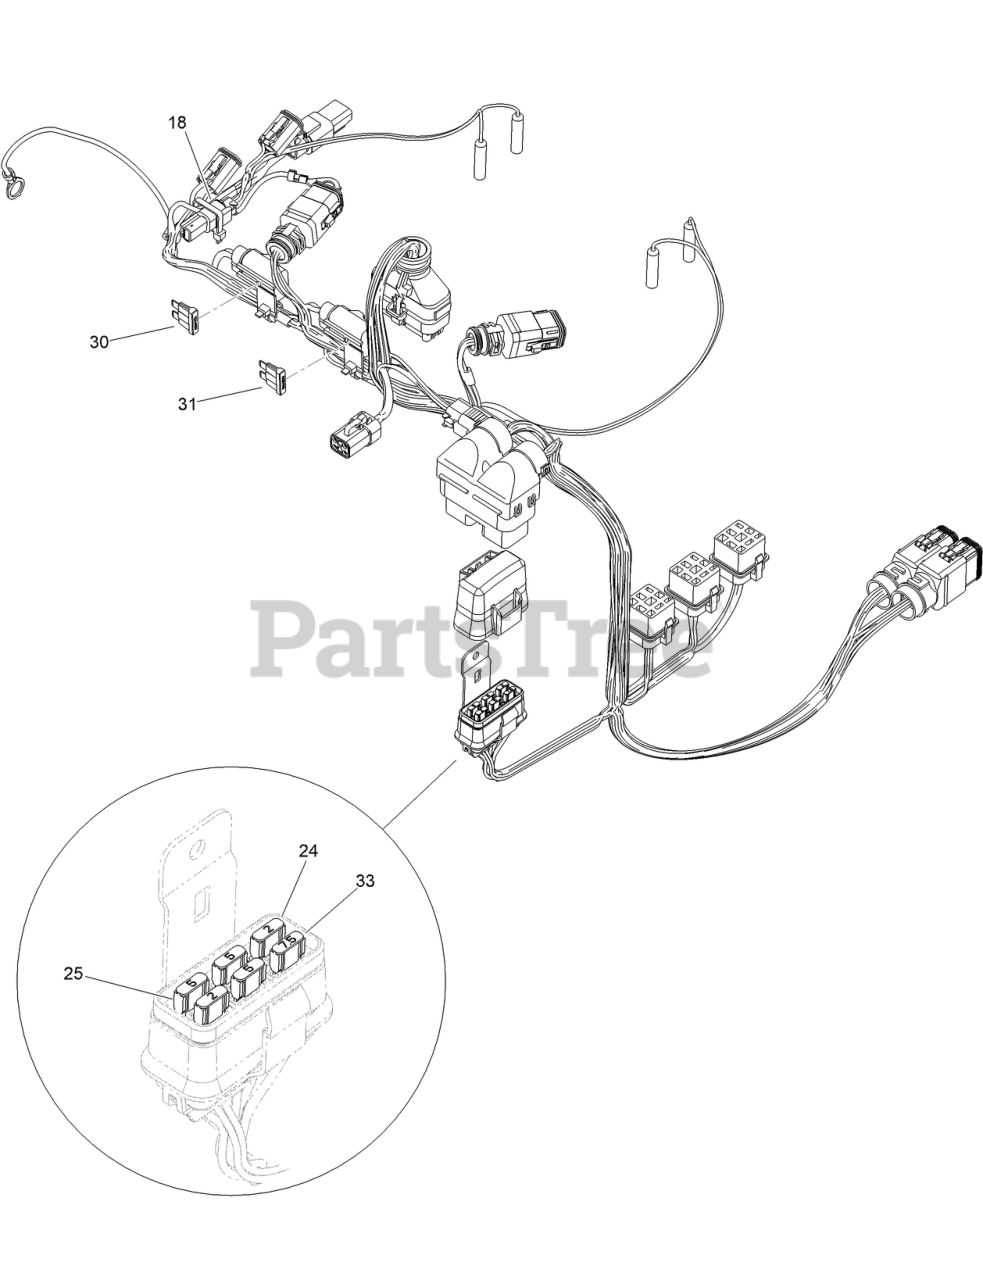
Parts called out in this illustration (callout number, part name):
18	RESISTOR-120 OHM
24	FUSE-MINI BLADE, 2 AMP
25	FUSE-MINI BLADE, 5 AMP
30	FUSE-BLADE, 10A
31	FUSE-BLADE, 15A
33	FUSE-MINI BLADE, 7.5 AMP
